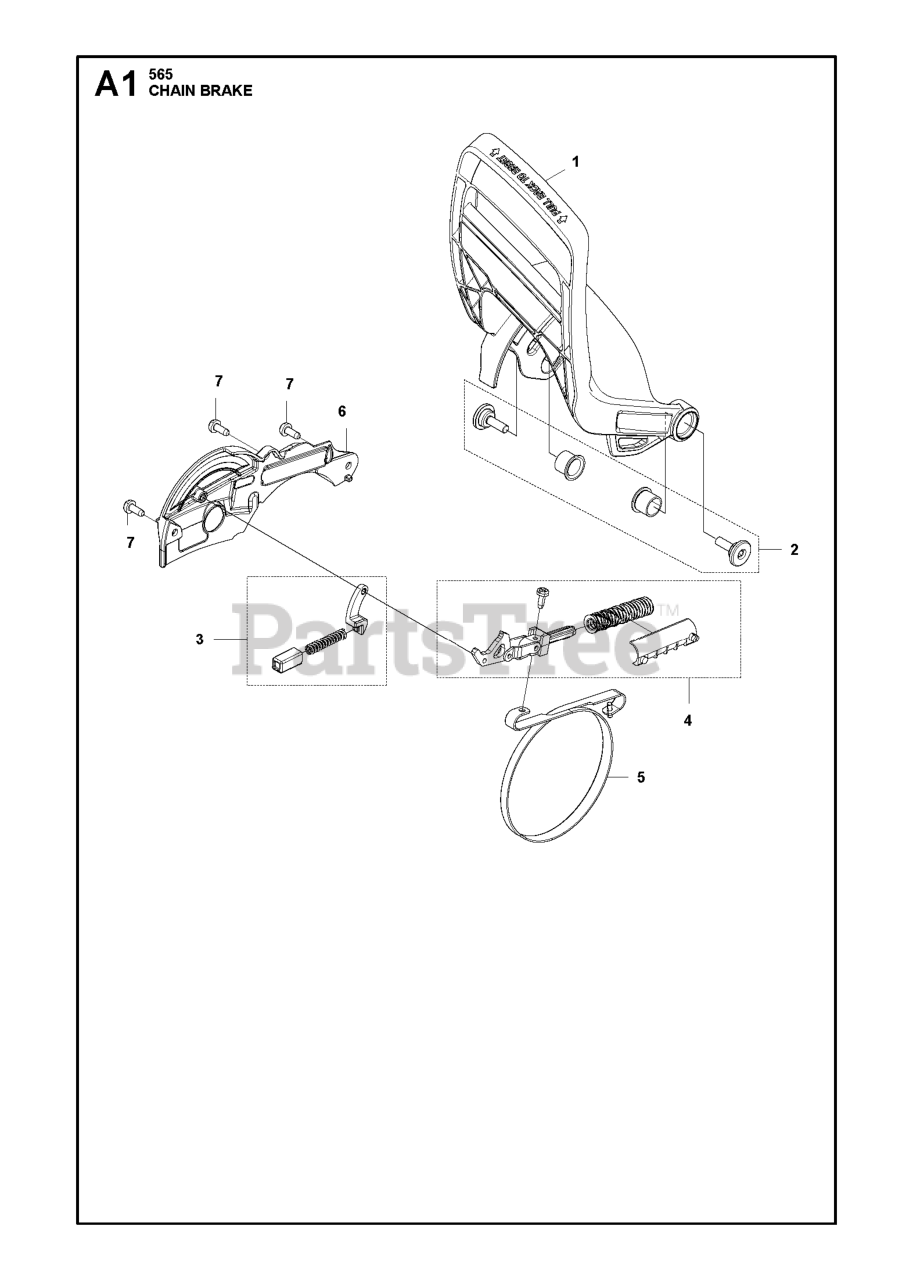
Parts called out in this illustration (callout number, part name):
1	HAND GUARD H565/H572
2	HAND GUARD BUSHING AND SCREW K
3	CHAIN BRAKE LOCK KIT H565/H572
4	KNEE JOINT KIT H565/H572
5	BRAKE BAND
6	COVER BRAKE
7	SCREW HEXALOBULAR PAN HEAD M4
